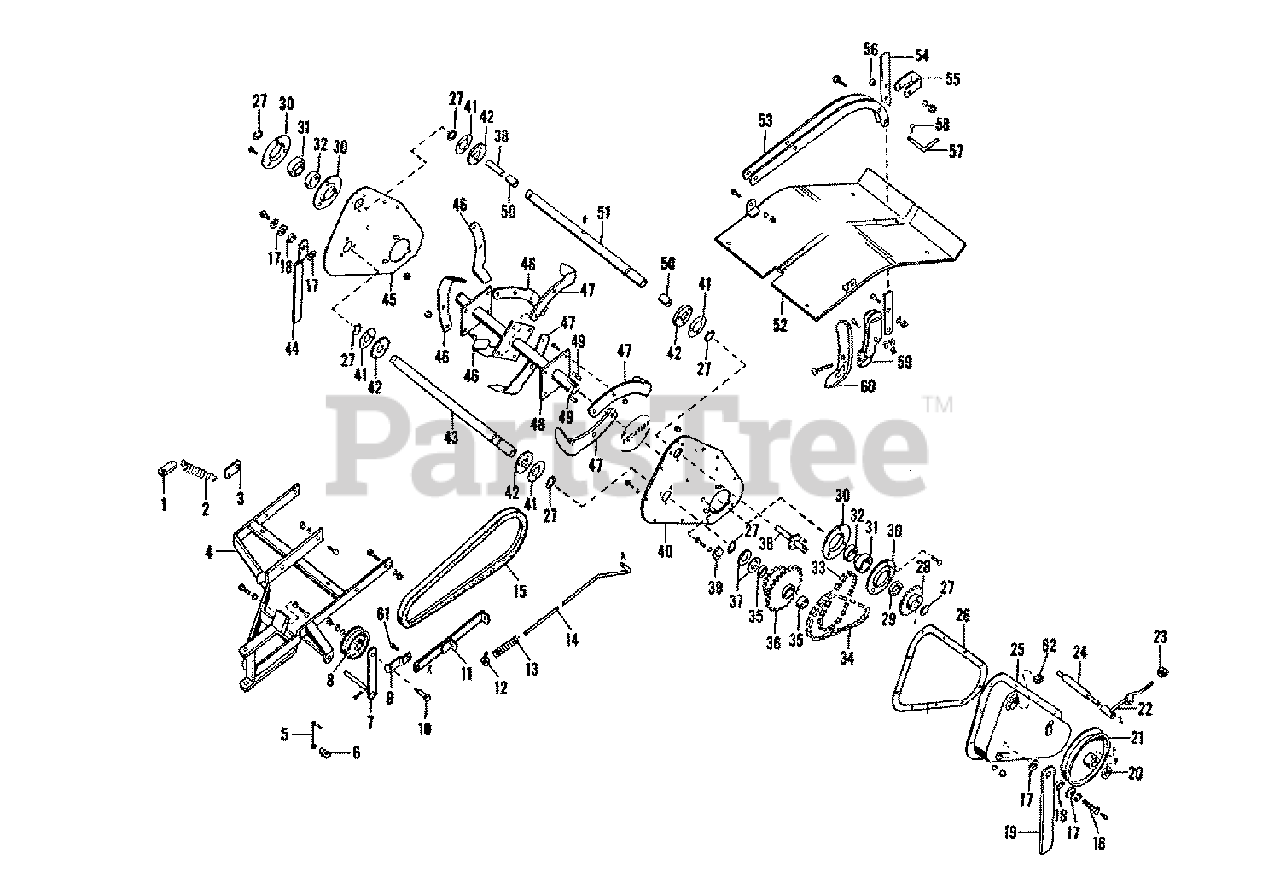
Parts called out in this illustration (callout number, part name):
1	HOLDER, Spring (Upper)
3	HOLDER, Spring (Lower)
4	FRAME ASSEMBLY
5	BELT, Stop
7	LEVER ASSEMBLY, Idler
8	PULLEY ASSEMBLY, Idler
9	EXTENSION, Idler Lever
10	IDLER PULLEY, Pin
11	GUIDE ASSEMBLY, Rod
12	SET, Collar
14	IDLER CLUTCH, Rod
15	V" BELT, 56" Long`
19	STAND, L.H.
20	COLLAR
21	SHEAVE, Drive
22	LEVER ASSEMBLY, Clutch
23	BALL, Lever
24	CLUTCH LEVER, Stud
25	GUARD ASSEMBLY
27	RING, Snap
28	SPROCKET, Driven
29	SPACER, Sprocket
30	FLANGE, Bearing
32	COLLAR, Bearing
33	CHAIN, Countershaft
34	ROTOR, Chain
36	SPROCKET ASSEMBLY
37	WASHER, Thrust
38	SHAFT ASSEMBLY, Drive
39	TIGHTENER, Chain
40	PLATE, L.H. Side
42	CLAMP, Plate
43	SHAFT, Counter
44	STAND, R.H.
45	PLATE ASSEMBLY, R.H.
46	TINE BLADE, L.H.
47	TINE BLADE, R.H.
48	TINE SHAFT ASSEMBLY
51	HOUSING, Drive Shaft
52	DEFLECTOR ASSEMBLY
53	BEAM, Depth Gauge
54	BAR, Depth
58	CLIP, Spring
59	HOLDER ASSEMBLY, Tool
60	SHOE, Depth
61	SCREW, Extension
